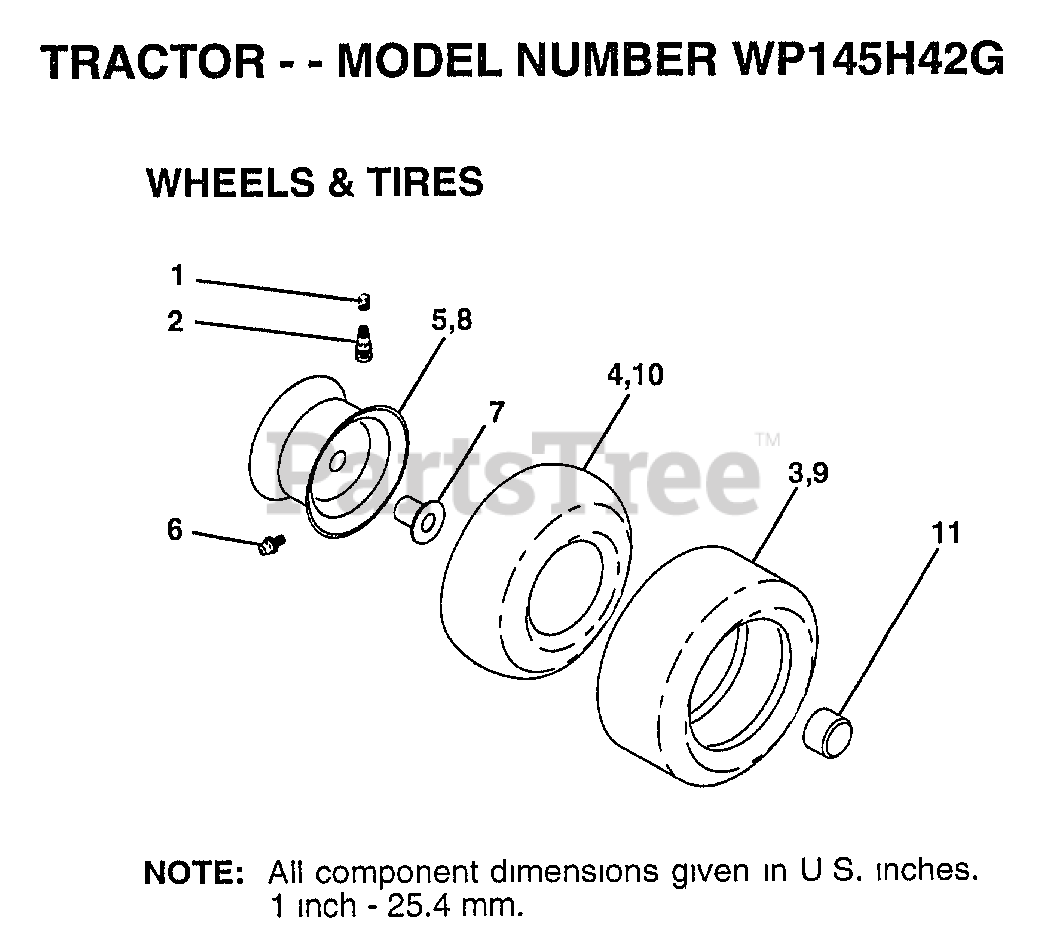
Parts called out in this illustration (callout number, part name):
1	VALVE CAP
2	VALVE STEM LT
4	TUBE.5.3/4.5/6
5	"RIM,FRT T"
6	FITTING LT
7	"FLANGE, BEARING"
8	"RIM 8"""
9	TIRE.20X8-8
10	TUBE.18X9.5-8
11	HUB CAP
